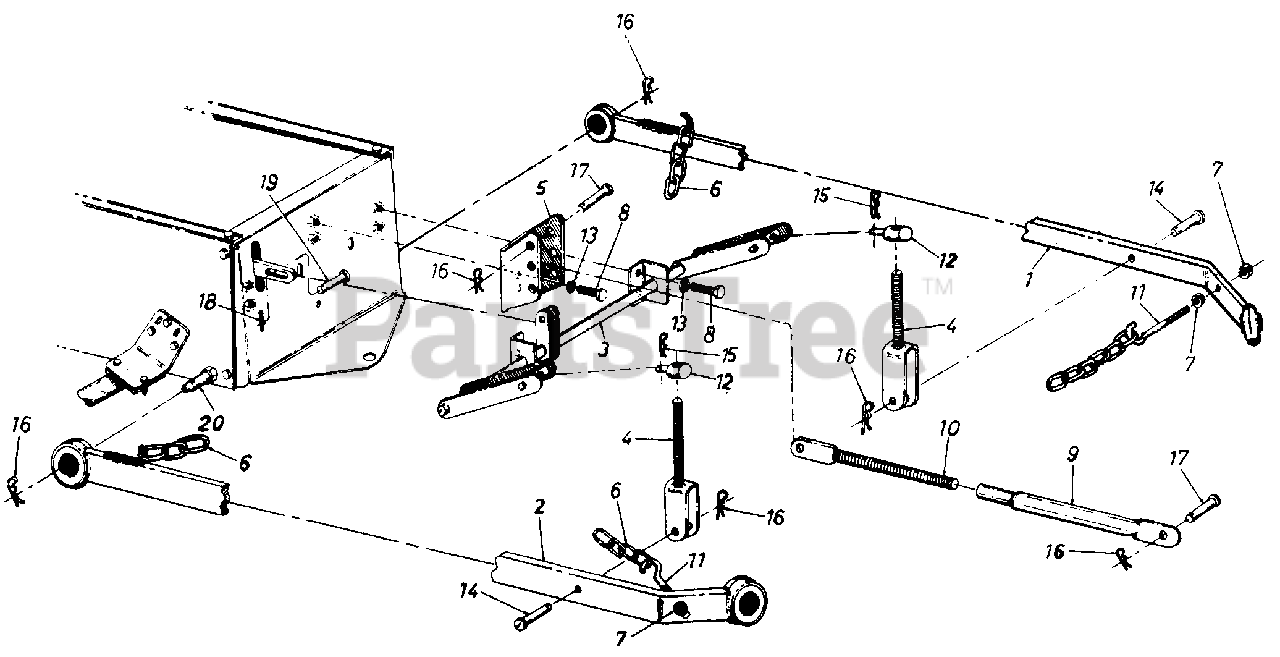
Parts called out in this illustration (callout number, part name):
1	Draft Bar Assembly-R.H.
2	Draft Bar Assembly-L.H.
6	Chain 20 Links
7	Hex Cent. L-Nut 7/16-14 Thd.
8	Hex Bolt 5-3/8-16 x 1 Lg. Grade 5
10	Clevis Screw
11	Hitch Chain Hook
13	L-Wash. 3/8" I.D.
14	Clevis Pin 5/8 Dia. x 1.66 Lg.
17	CIevis Pin 5/8 Dia. x 2.4 Lg.
18	Cotter Pin 1/8 Dia. x 1-1/4 Lg.
20	Link Clevis Pin
